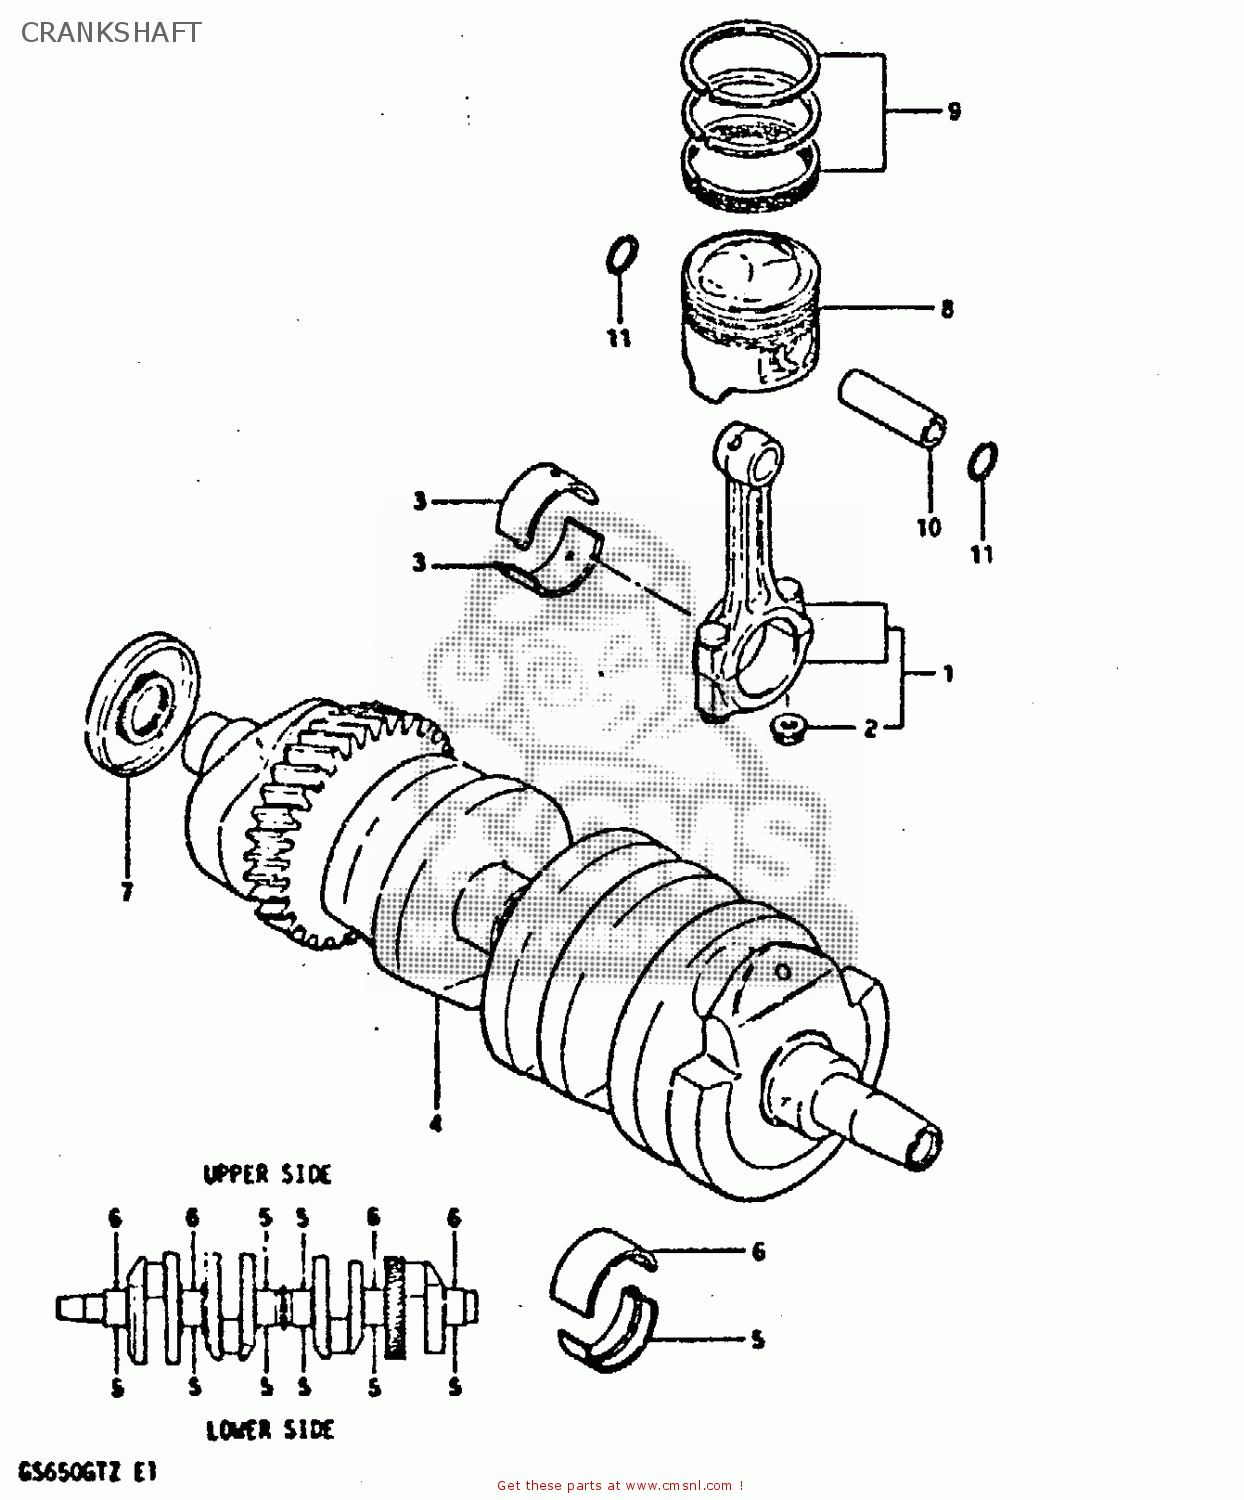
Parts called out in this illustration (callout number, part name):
1	ROD ASSEMBLY,CONNECTING
2	NUT
3	BEARING,CRANK PIN
4	CRANKSHAFT
5	METAL CRANKSHAFT
6	METAL CRANKSHAFT
7	OIL SEAL
8	PISTON
9	RING SET,PISTON
10	PIN,PISTON
11	CIRCLIP
